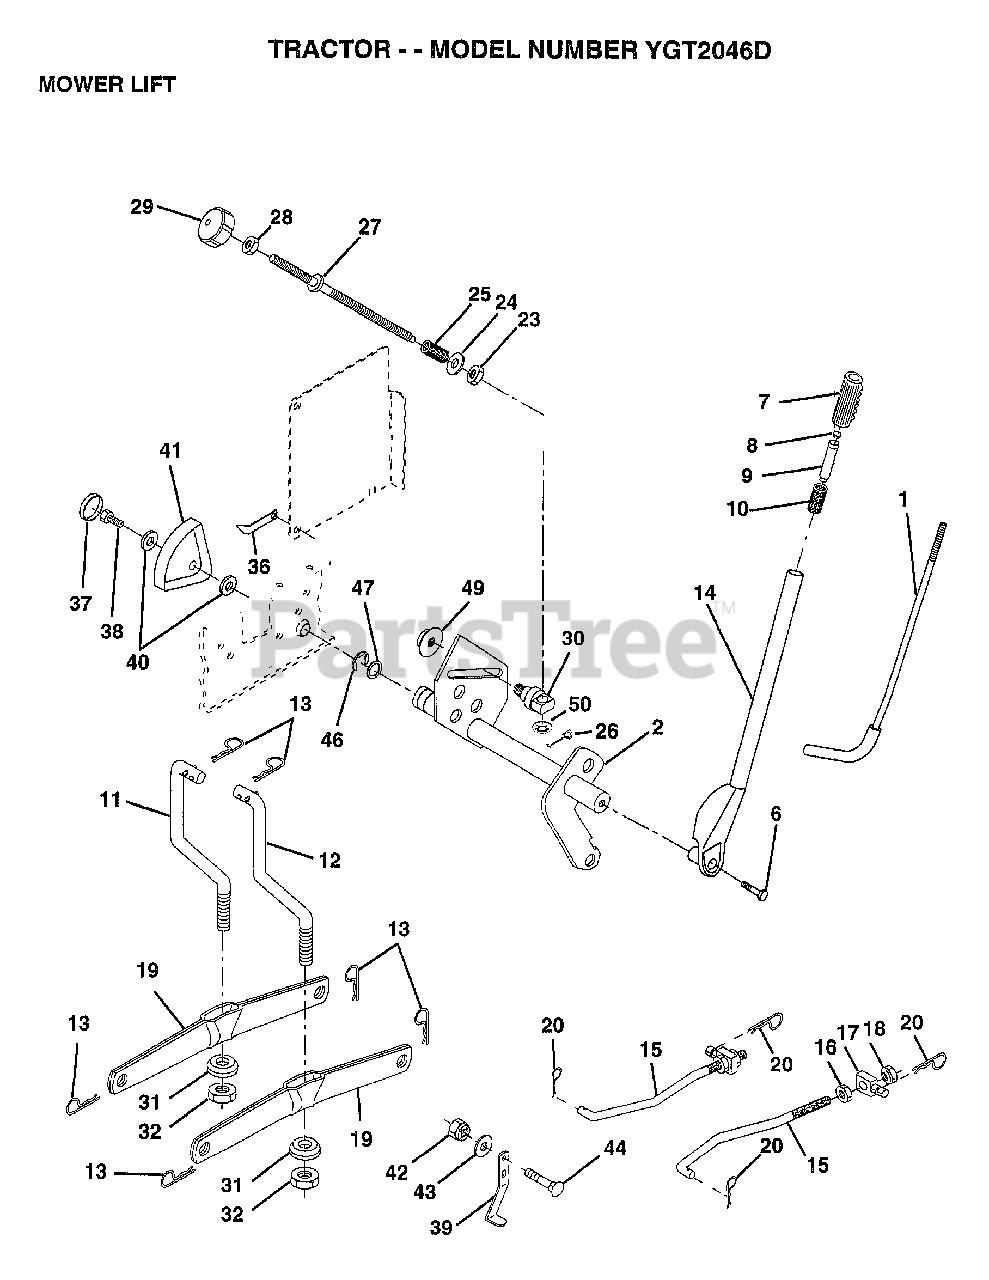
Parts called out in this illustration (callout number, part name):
1	LEVER ROD LT
2	LEVER ASSY LIFT.RH.
6	"BOLT,HEX"
7	GRIP HANDLE
10	SPRING T
11	LINK.LIFT.LH.GTV
12	LINK.LIFT.RH.GTV.
14	LEVER.ASM.LIFT.RH
15	LINK.FRONT
16	NUT
17	TRUNION
18	NUT LTV
19	ARM SUSP REAR
20	RETAINER SPRING
23	NUT T
24	WASHER
25	SPRING.COMP.INF.H
27	ROD.ADJ.LIFT
28	NUT
29	KNOB INF 3/8-16
30	TRUNNION
31	BEARING PVT LH
32	NUT.CROWNLOCK.3/8
36	POINTER HEIGHT INDICATOR
37	"PLUG,HOLE"
38	SCREW
39	STOP.OVER.CENTER
40	WASHER
41	HEIGHT INDICATOR
43	WASHER GT
44	BOLT
46	E-RING
47	WASHER
49	NUT.HXFLG.LOCK.
50	NUT PUSH M
